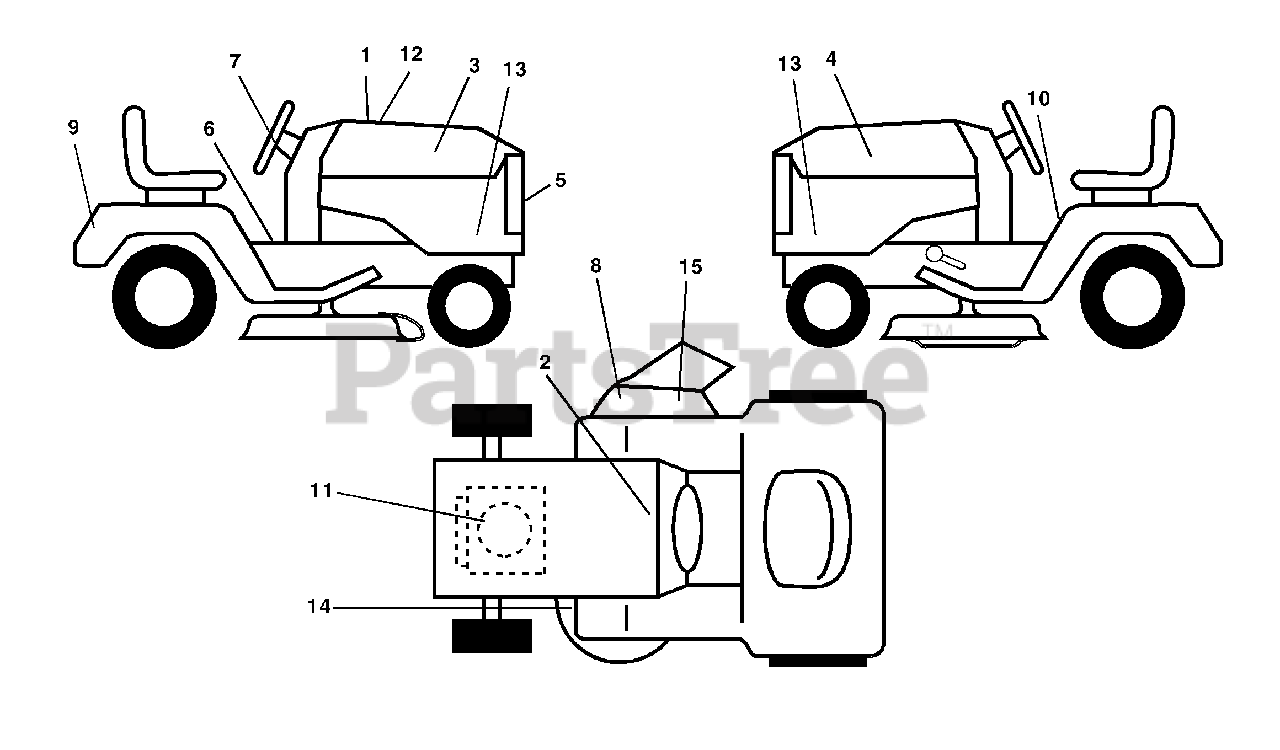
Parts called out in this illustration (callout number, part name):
1	Decal Hood Cust. Resp.
2	Decal Battery
3	Decal Hood RH
4	Decal Hood LH
5	Decal Grille
6	Decal Fender Oper
7	Decal Wheel Steering
8	Decal Warning Keep Hand Away
9	Decal Fender Husq
10	Decal Fender Danger E/F
11	Decal Engine
12	Decal Hood
13	Decal Hoodsides Kawa VTWN
14	Decal V-Belt Schematic
15	Decal Deck "B" 42"
